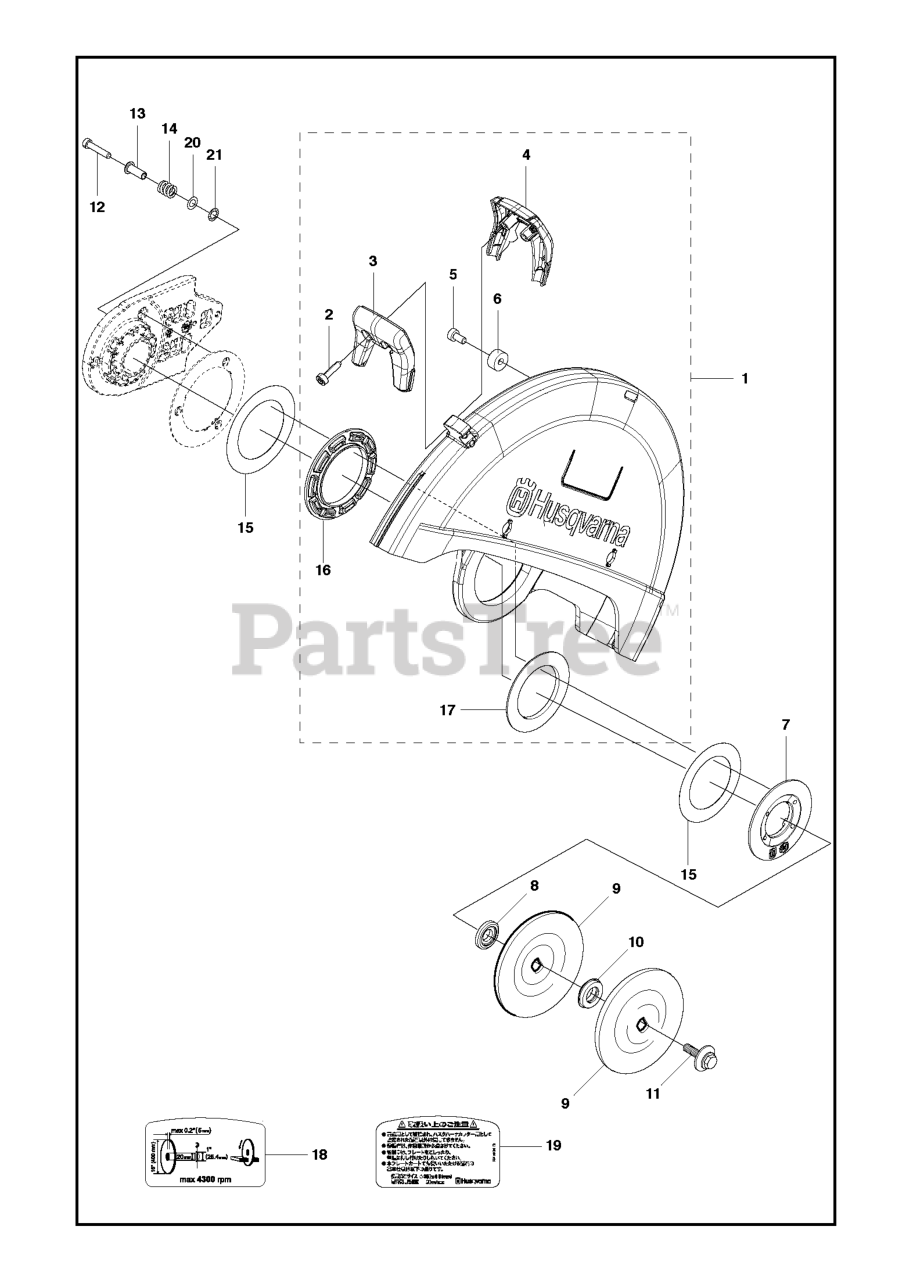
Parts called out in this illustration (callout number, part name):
1	WHEEL GUARD ASSY 16" MG UNIVER
1	WHEEL GUARD ASSY 14" MG UNIVER
3	HANDLE HALF
4	HANDLE HALF
6	STOP WHEEL GUARD MG
7	DISC HOLDER BEARING HOUSING
8	SUPPORT FLANGE
9	WASHERS
9	FLANGE D105MM/3MM DOMEX 13MM B
10	BUSHING
10	BUSHING ASSY BLADE WITH O-RING
11	SCREW ASSY M10 BLADE
12	SCREW ITXSCM M6X30 T27 10.9 Z
13	SLEEVE SPRING BLACK
13	SLEEVE SPRING SHINY
14	SPRING WHEEL GUARD
15	SHIM WHEELGUARD BEARING
16	LINING BEARING HOUSING
17	LINING DISC
18	DECAL MG BLADEGUARD BUSHING SI
19	DECAL
20	WASHER 8.3X13.5X0.5 ST ZPB
21	WASHER 7.6X13.5X0.215 PTFE
